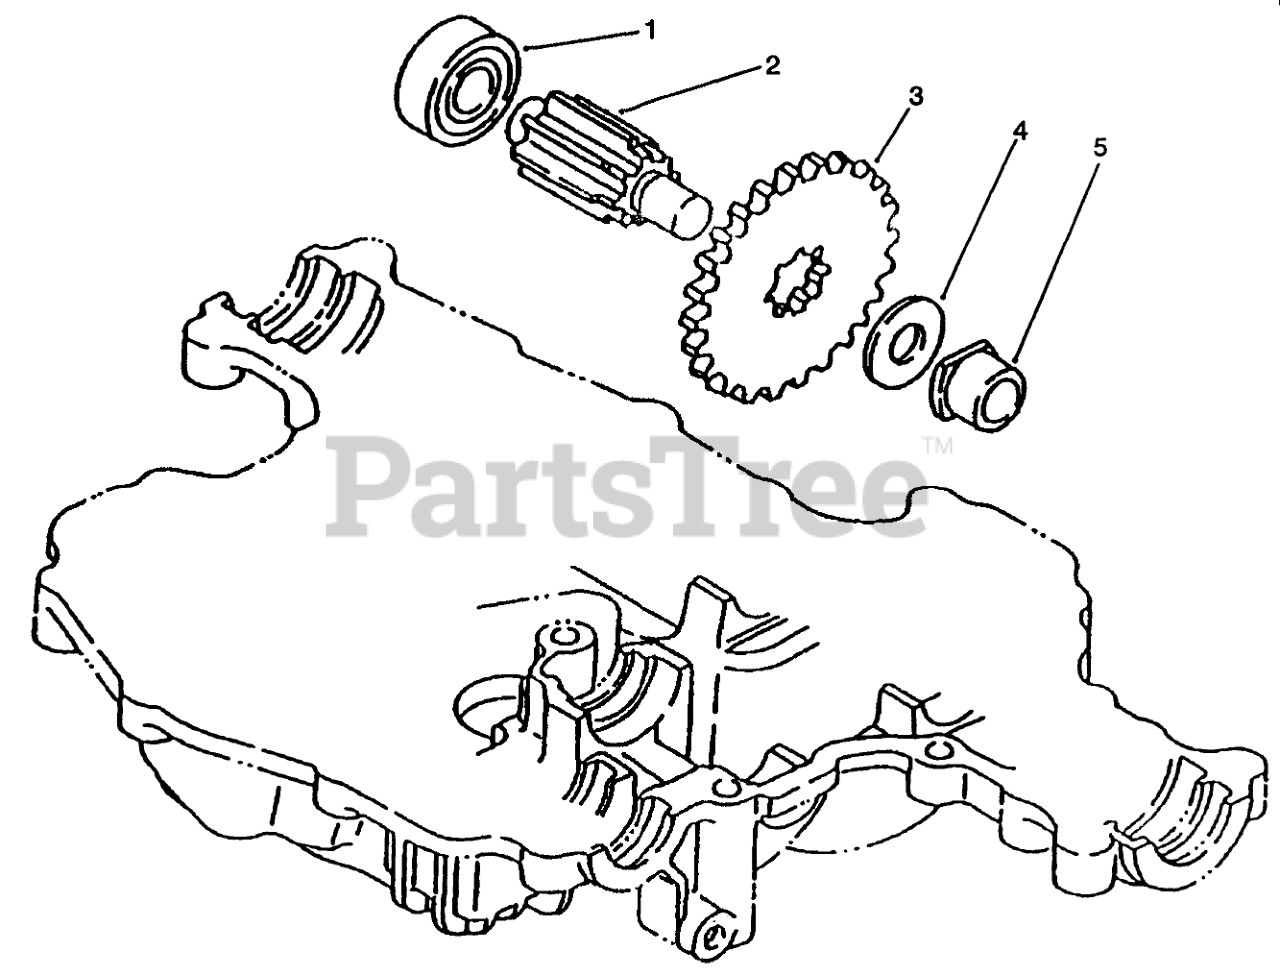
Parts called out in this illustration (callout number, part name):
1	Bearing (Only On: 72083, 72043, 72103, 72063)
2	Shaft-Final Pinion (Only On: 72083, 72043, 72103, 72063)
3	Gear-Final Shaft (Only On: 72083, 72043, 72103, 72063)
4	Washer (Only On: 72083, 72043, 72103, 72063)
5	Bushing (Only On: 72083, 72043, 72103, 72063)
